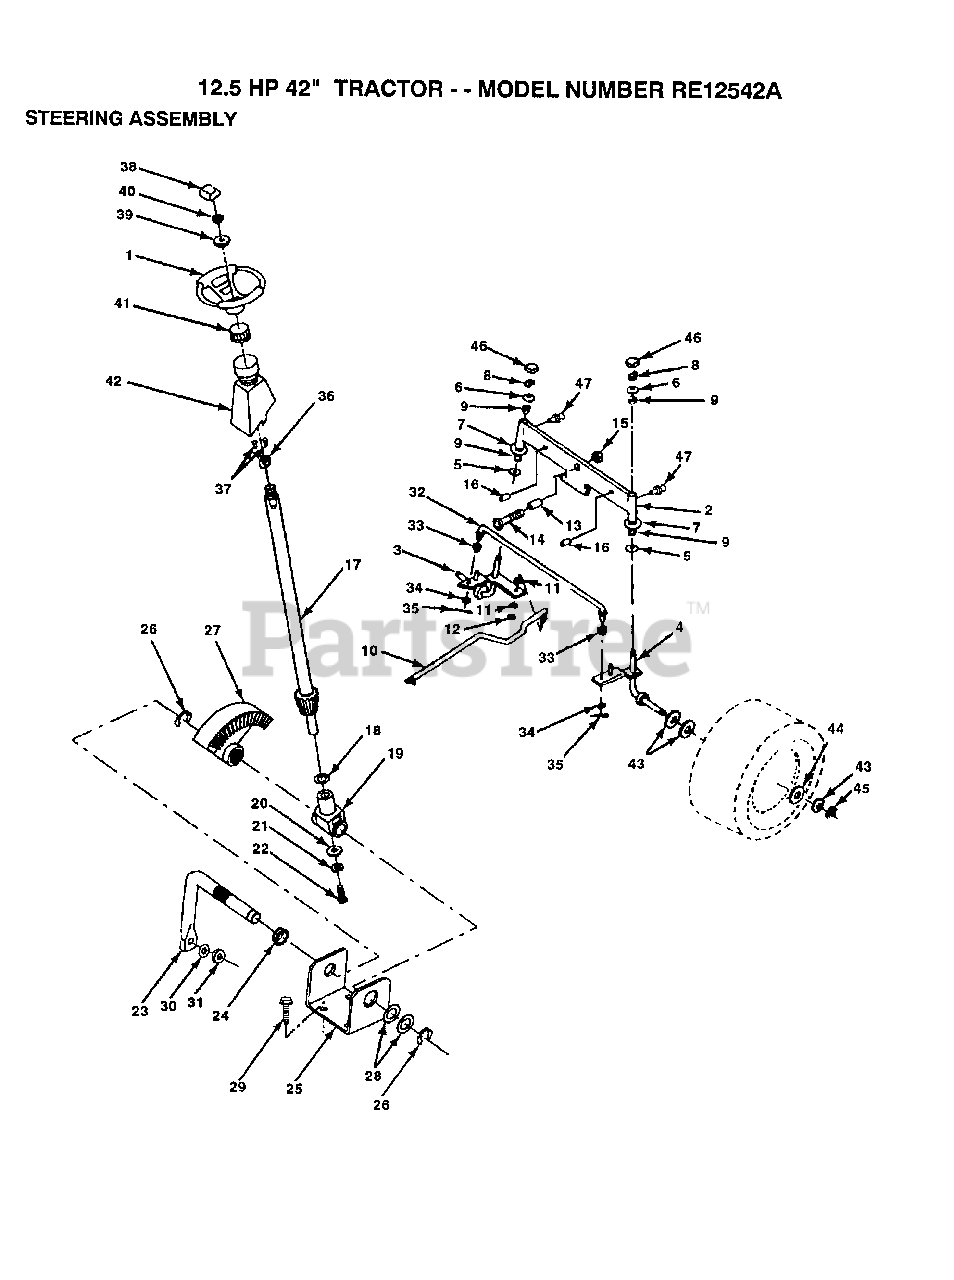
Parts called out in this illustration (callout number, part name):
3	SPINDLE LH
4	SPINDLE RH
5	WASHER .T
6	WASHER
7	WASHER
8	RING
9	COL. SRTG. BEAR.
11	LOCKWASHER
13	BEARING
14	BOLT HEX 5/8-11
16	AXLE PIN
17	SHAFT ASM
18	THRUST WASHER
19	SUPPORT.SHAFT
21	LOCKWASHER
22	"SCREW,SPECIAL"
24	NYLINER T
25	"BRKT,STEERING"
26	RING
28	WASHER .T
29	SCREW
30	LOCKWASHER
32	TIE ROD
33	BUSHING.DRAGLINK
34	WASHER
35	COTTER PIN
38	ST WHL INSERT CAP
39	WASHER T
40	GRIPCO NUT
41	ADAPTER-WHEEL LT
42	"TUBE, STR SHAFT"
43	WASHER
44	WASHER
45	RING
46	CAP
47	ZERK M
